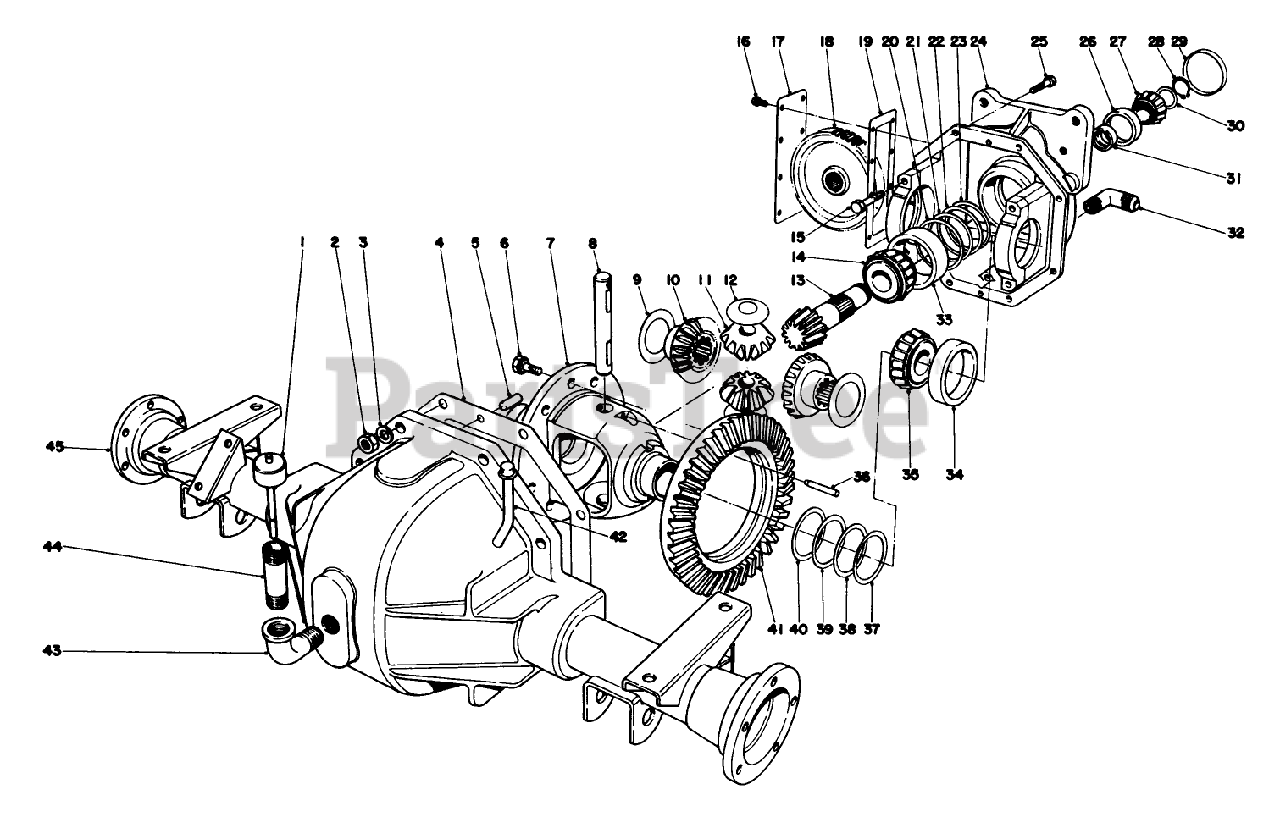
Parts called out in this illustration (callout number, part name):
1	DIPSTICK
2	NUT-HEX
3	WASHER-LOCK
4	HSG GASKET
5	PIN-DOWEL
6	SCREW-GEAR, DRIVE
7	CASE-DIFFERENTIAL
8	SHAFT-MATE, PINION
9	WASHER-THRUST
10	GEAR-DIFFERENTIAL
11	PINION-DIFFERENTIAL
12	WASHER-THRUST, PINION
14	ROLLER BRG CONE
15	SCREW-HH
16	SCREW
17	COVER-GEAR
18	Gear-Spur
19	GEAR COVER GASKET
20	REAR PINION BRG SHIM
21	BRG SHIM .005
22	BRG SHIM .010
23	BRG SHIM .030
24	Upper Housing Assembly
25	Screw
26	BEARING-CUP
27	BRG CONE
28	Retaining Ring
29	PLUG-CUP
30	FRT PINION BRG SHIM
31	SPACER-BEARING
32	90 DEG FITTING
33	ROLLER BRG CUP
34	CUP-BEARING, ROLLER
35	BEARING-ROLLER, CONE
36	Pin-Roll
37	SHIM-BEARING, DIFFERENTIAL (.003)
38	SHIM-BEARING, DIFFERENTIAL (.005)
39	SHIM-BEARING, DIFFERENTIAL (.010)
40	SHIM-BEARING, DIFFERENTIAL (.030)
41	Ring Gear
42	Vent Assembly
43	FITTING-ELBOW-90
44	PIPE NIPPLE
45	Lower Housing Assembly
